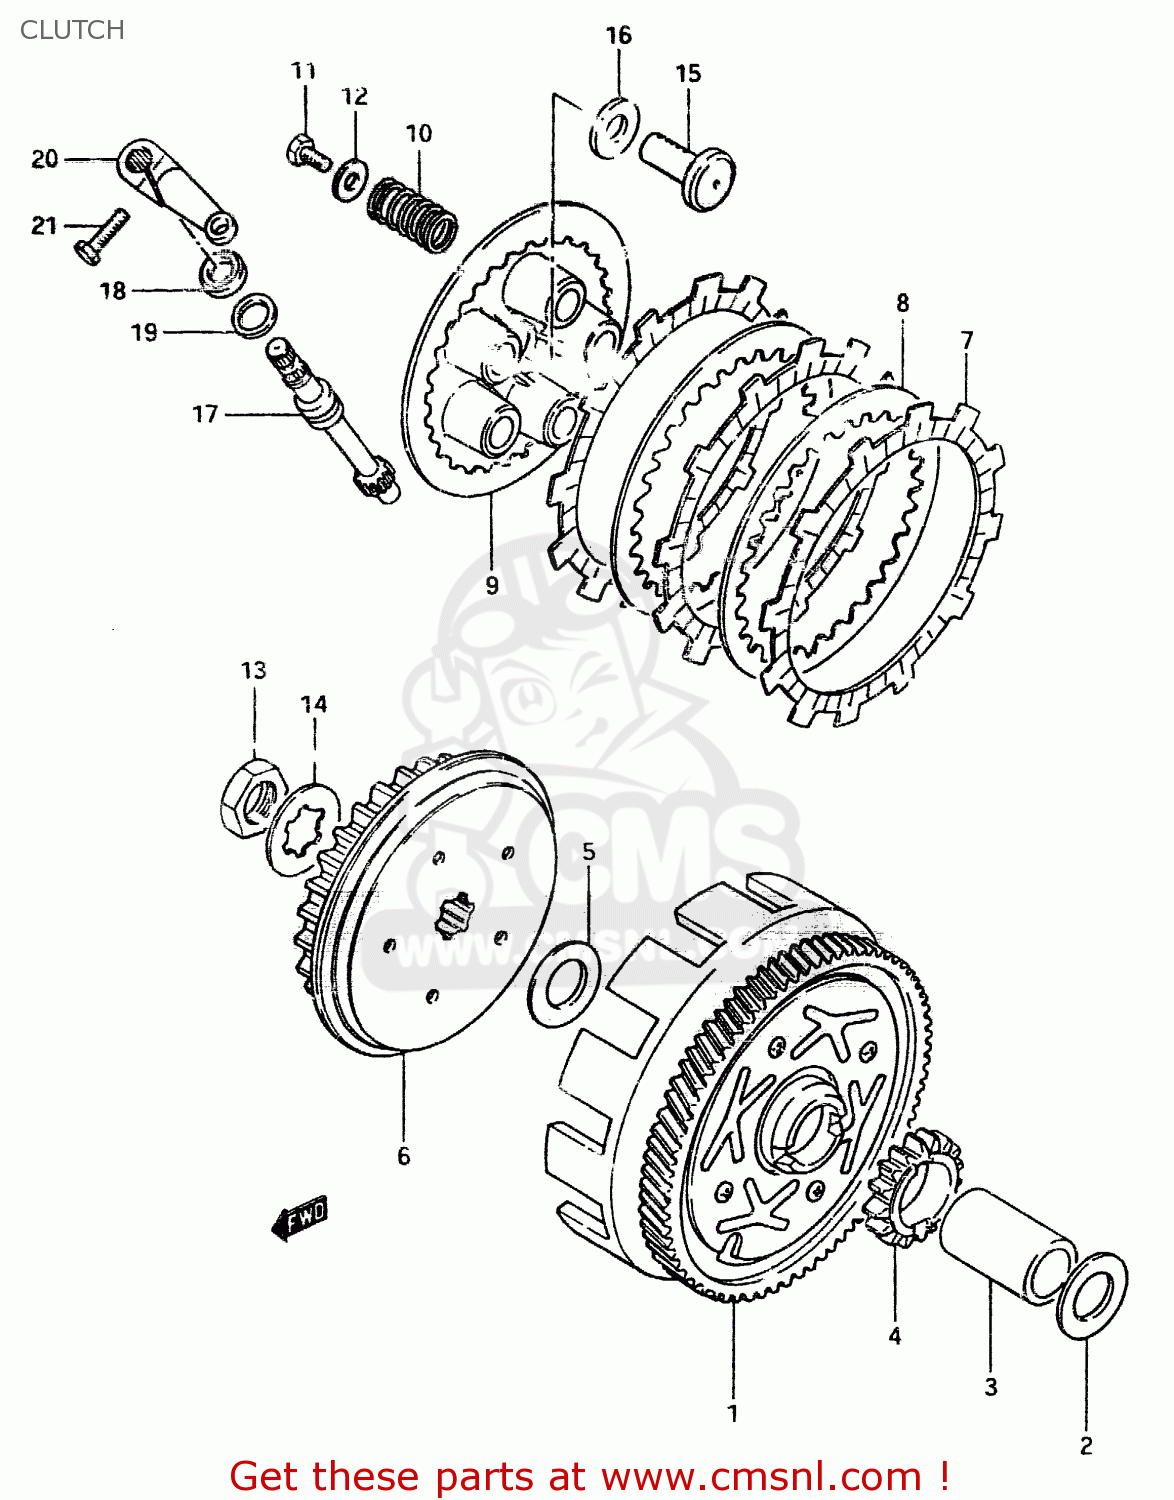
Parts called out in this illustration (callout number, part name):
1	GEAR ASSEMBLY,PRIMARY DRIVE
2	WASHER,THRUST
3	SPACER
4	GEAR,KICK STARTER DRIVE
5	WASHER
6	HUB,CLUTCH SLEEVE
7	PLATE,CLUTCH DRIVE
8	PLATE,CLUTCH DRIVEN (NAS)
9	DISC,CLUTCH PRESSURE
10	SPRING
11	BOLT(5X16)
12	WASHER (5.5X16X1.2)
13	NUT
14	WASHER,LOCK
15	RACK,CLUTCH RELEASE
16	BEARING(10X22X2.8)
17	PINION,CLUTCH RELEASE
18	OIL SEAL
19	WASHER (12X17X1)
20	ARM,CLUTCH RELEASE
21	BOLT, UPPER
